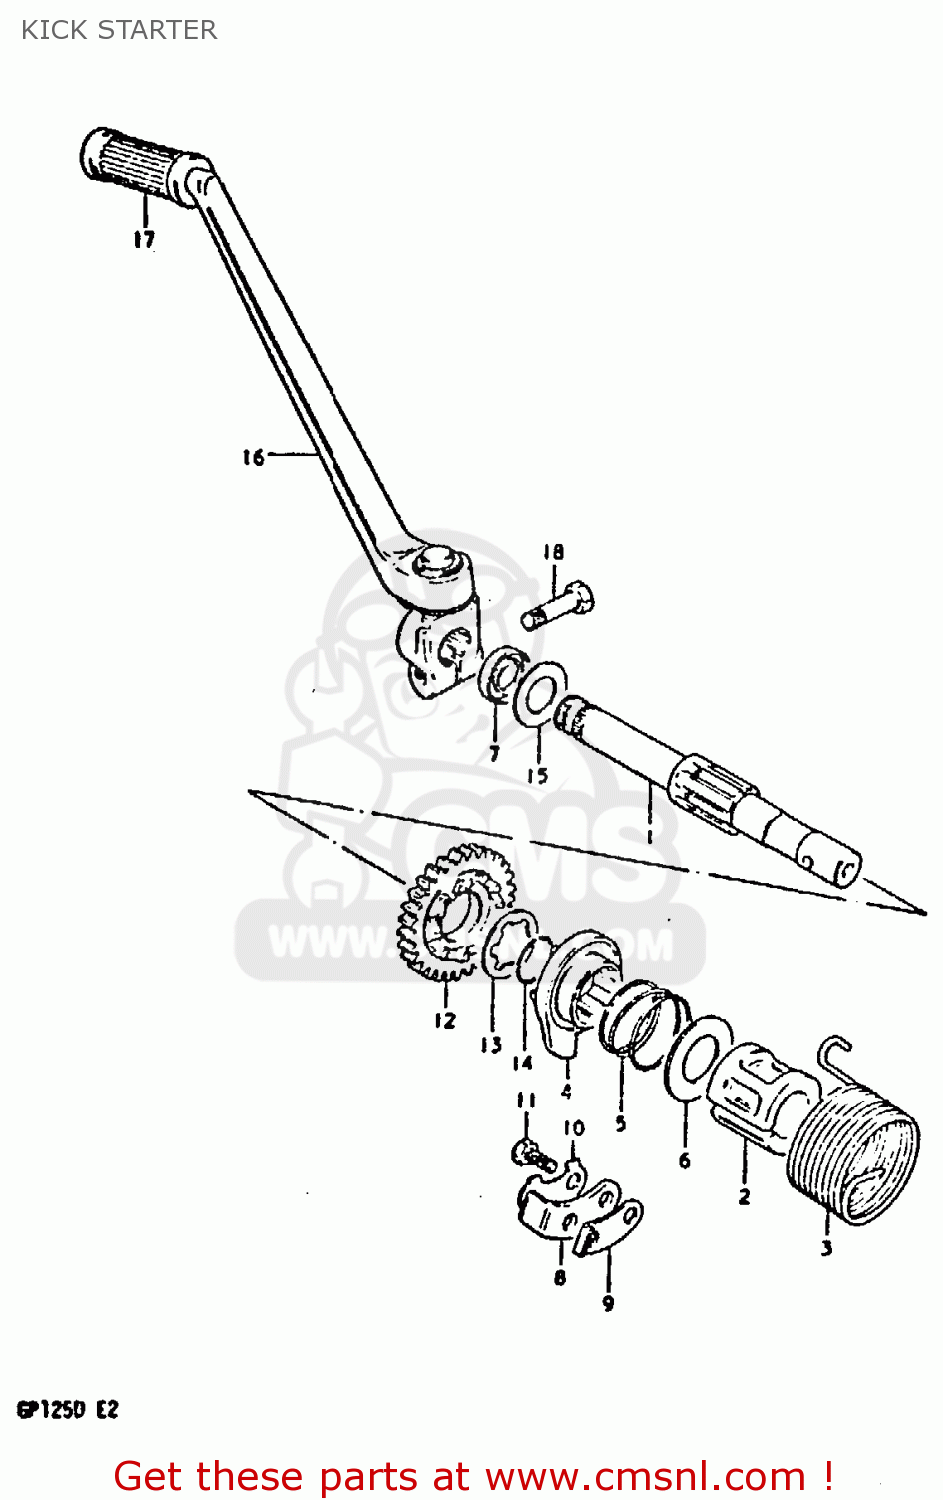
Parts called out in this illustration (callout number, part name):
1	SHAFT,KICK STARTER
2	GUIDE,KICK STARTER SFT SPRING
3	SPRING
4	STARTER,KICK
5	SPRING
6	WASHER
7	SEAL,OIL(16X30X8)
8	GUIDE,KICK STARTER
9	STOPPER,KICK STARTER
10	WASHER
11	BOLT, UPPER
12	GEAR,KICK STARTER DRIVE
13	WASHER,LOCK
14	CIRCLIP
15	WASHER(16X30X1)
16	LEVER ASSY,KICK STARTER
17	RUBBER,KICK STARTER PEDAL
18	BOLT
